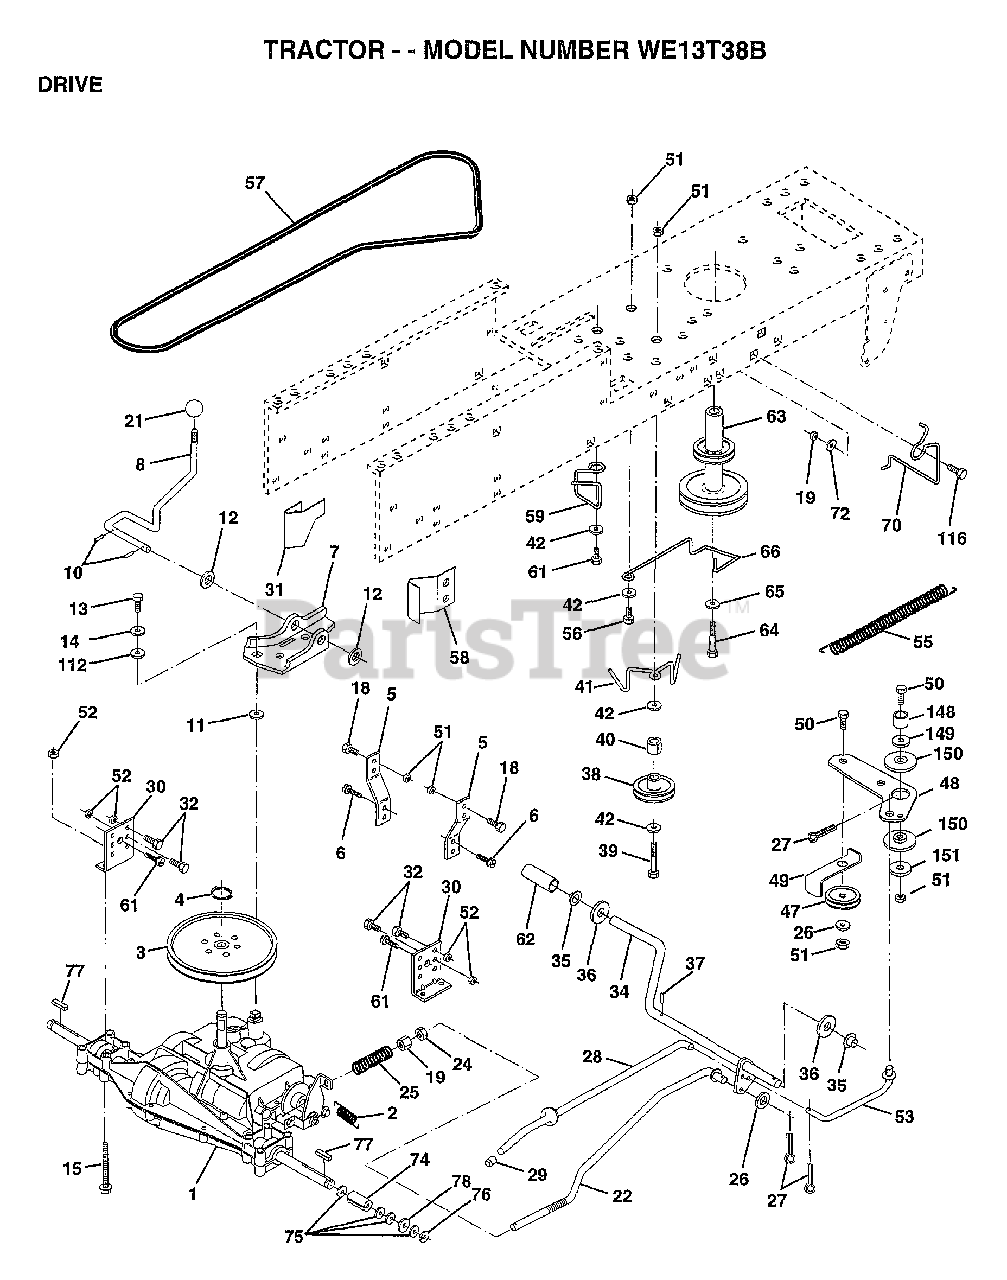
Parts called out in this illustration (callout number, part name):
2	SPRING.BRAKE.RETU
3	PULLEY TRANS
5	STRAP TORQUE
6	SCREW
7	BRKT.SADDLE.SHIFT
8	SHIFT ROD
10	PIN COTTER 1/8
11	WASH-SHFT PLT LT
12	WASHER
13	BOLT.1/4-28.W/PAT
14	LOCKWASHER
15	BOLT.HX.FLG.5/16
18	BOLT
19	NUT
21	KNOB T (1/2-HOLE)
22	BRAKE ROD
24	NUT
25	SPRING ROD LT
26	WASHER
27	COTTER PIN
28	ROD.BRAKE.PARK.LT
29	PLUNGER CAP T
30	TRANSAXLE MTG BKT
31	"KEEPER,BELT LH T"
32	BOLT
34	SHAFT ASM-PEDAL F
35	NYLON BEARING
36	WASHER LT
38	PULLEY.IDLER.FLAT
39	BOLT
40	SPACER T
42	WASHER
48	BELLCRANK.CLUTCH
49	RETAIN BELT
53	"LINK, CLUTCH T"
55	"SPRING, RETURN LT"
57	"V-BELT,95.3"
58	"KEEPER,BELT RH T"
59	KEEPER BELT CNTSP
61	SCREW
62	PEDAL COVER T
63	PULLEY.ENGINE
64	BOLT
65	LOCKWASHER
66	KEEPER-BELT
70	KEEPER BELT ENG
72	WASHER
74	SPACER LT
75	WASHER
76	E-RING LT
77	SQUARE KEY
78	WASHER
112	WASHER LT
116	BOLT RDHD 3/8-16
149	SPACER RETAINER
150	BUSHING.NYLON
151	WASHER
